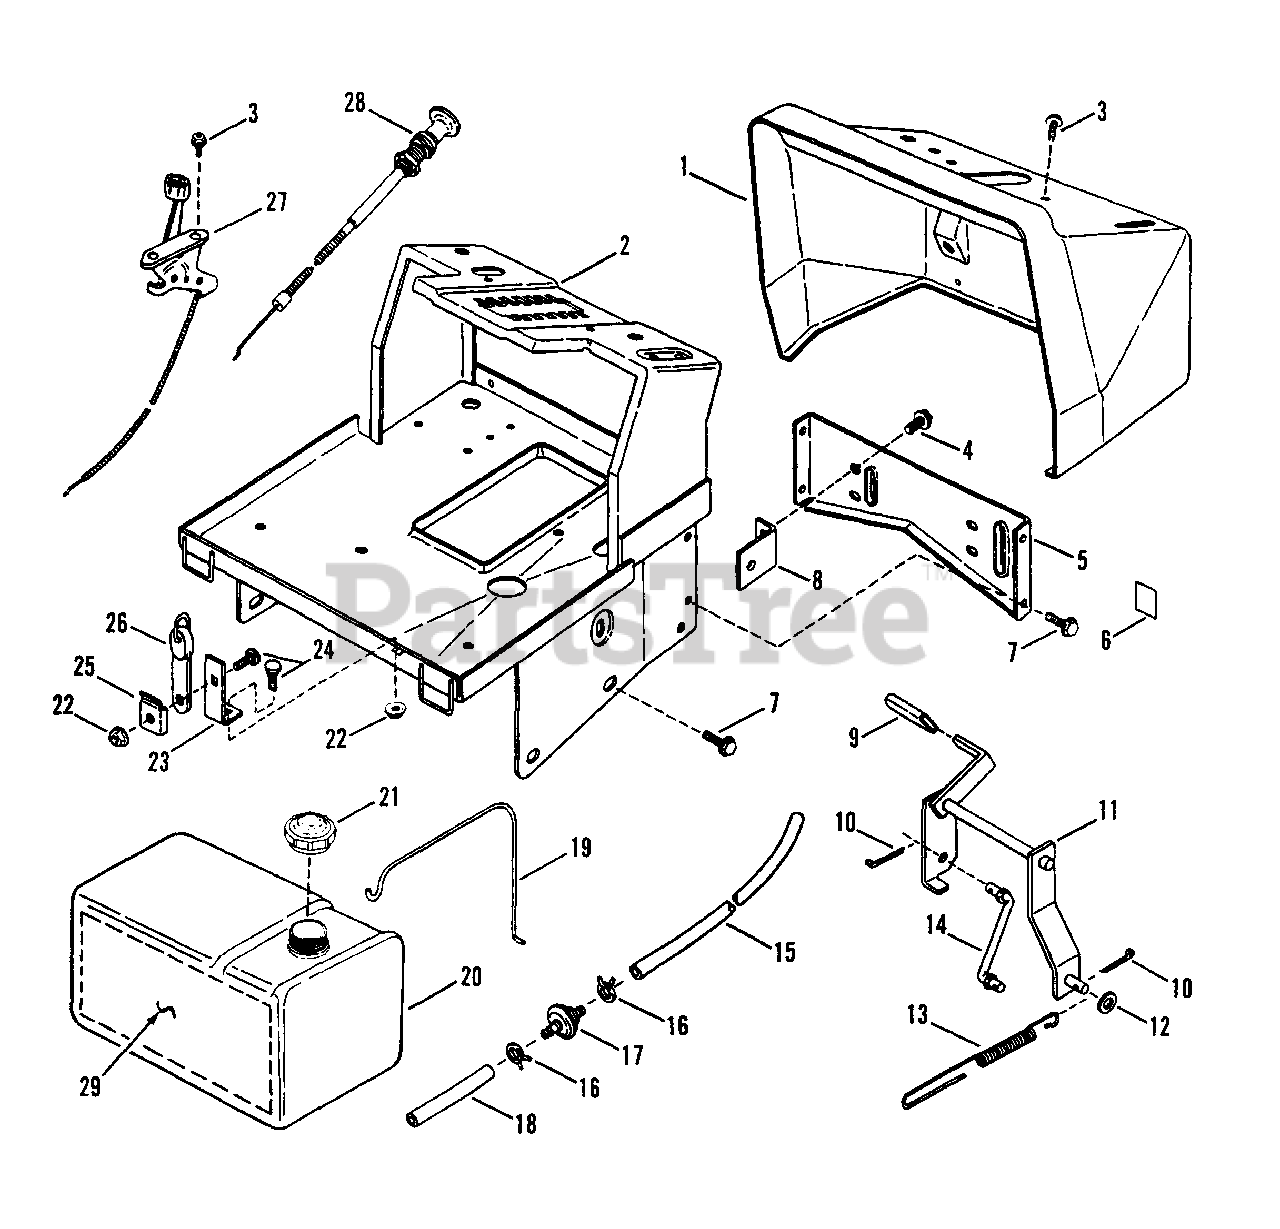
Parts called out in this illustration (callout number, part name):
1	PANEL, Dash
2	PEDESTAL
3	SCREW, #10-24 x 1/2" Hex Washer Self-Tap (Torx)
4	SCREW, 1/4-20 x 5/8" Truss Head, Torx
5	BRACKET, Lower Dash
6	DECAL, Cruise
7	SCREW, 5/16-18 x 5/8" Self- Tapping
8	BRACKET
9	SLEEVE, Parking Brake
10	COTTER-PIN
11	LEVER, Engagement
12	WASHER, 3/8 SAE Flat
14	LATCH ROD
15	LINE, Fuel (12.5" Long)
16	CLAMP, Fuel Line
17	FILTER, Fuel (In-Line)
18	LINE, Fuel (3" Long)
19	HOLD-DOWN, Fuel Tank
20	TANK, Fuel
21	CAP, Fuel Tank
22	NUT, 1/4-20 Hex Flange Top Thread Lock
23	BRACKET, Tank Hold-Down
24	BOLT, 1/4-20 x 5/8" Flat Head Carriage
25	CLIP, Hood Retainer
26	STRAP, Tank Hold-Down
27	CONTROL, Throttle
28	CONTROL, Choke Cable
29	HEAT SHIELD, Fuel Tank
